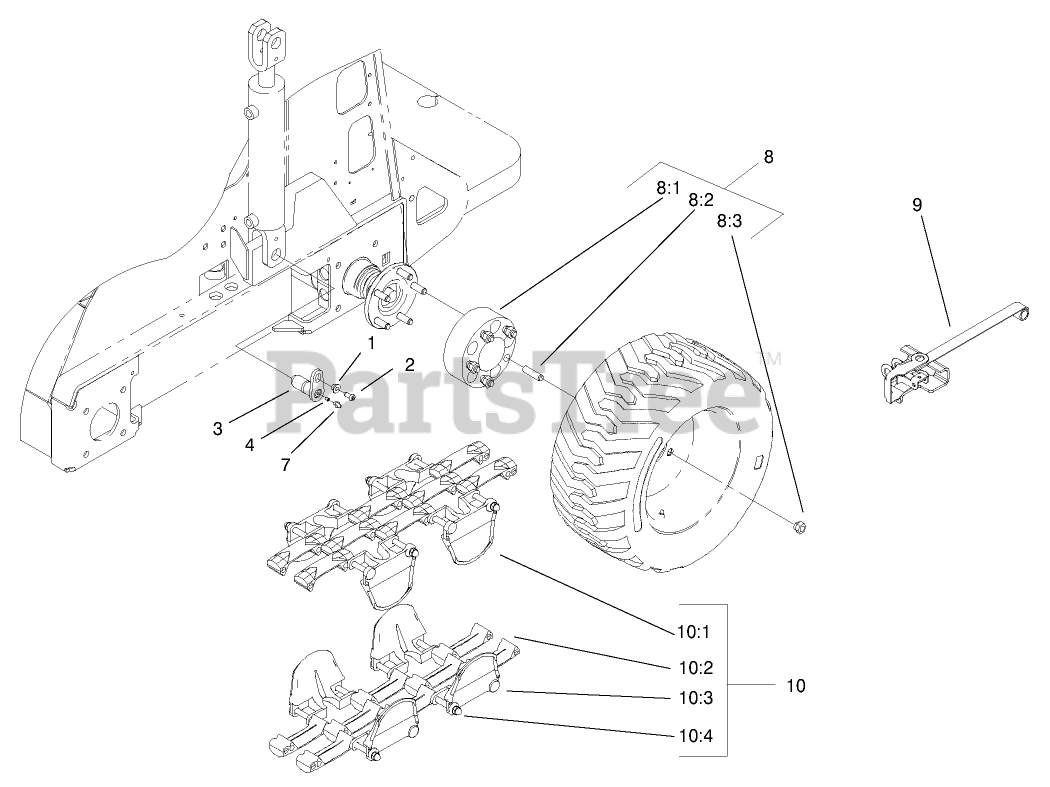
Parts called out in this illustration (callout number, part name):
1	BUSHING-FLANGE
2	SCREW-BUTTON HEAD
3	PIN-PIVOT
4	SCREW-SET, HSH
7	FITTING-GREASE
8	SPACER ASM
8:1	SPACER
8:2	STUD-TYPE, DRIVE
8:3	NUT-LUG
9	TOOL-INSTALLATION
10	LOEGERING TRACK ASM
10:1	PLATE-SIDE
10:2	LUG-INNER
